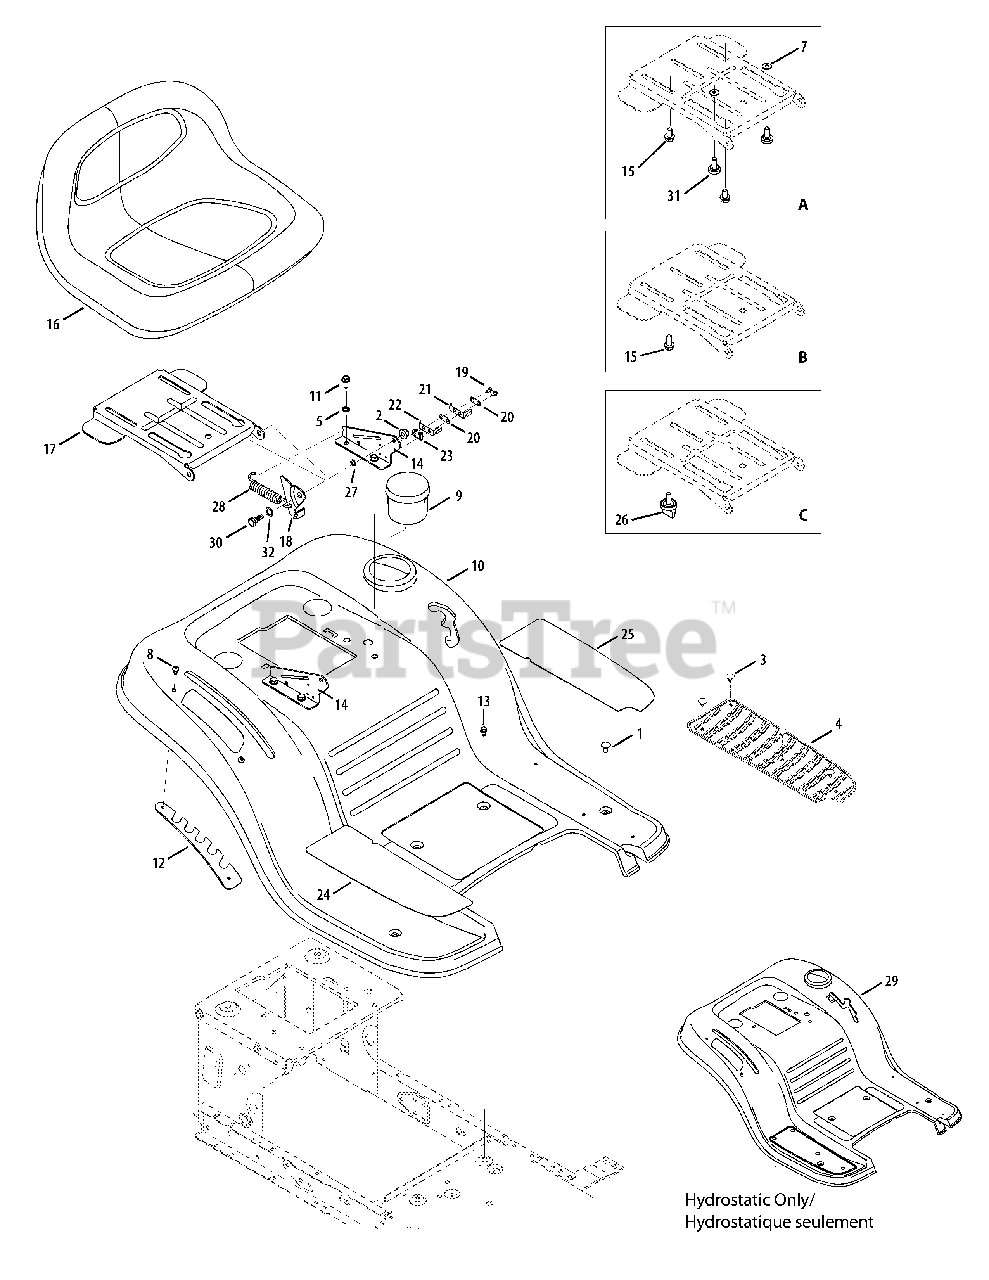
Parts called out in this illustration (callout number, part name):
1	Carriage Bolt 1/4-20 x .62
2	Flange Locknut 5/16-18 Gr. F, Nylon
5	Lockwasher 5/16 ID
6	Flat Washer .510 x .750 x .033
7	Flat Washer .405 x .875 x .059
7	Flat Washer .395 x .62 x .063
8	Tap Screw 1/4-20 x .50
11	S-Tapp Screw 5/16-18 x .75
13	Hex Wash S-Tapp Screw 1/4-20 x .50
15	Screw 3/8-16 x .875
16	Seat, Low Back
16	Seat, Medium Back
16	Seat, High Back
18	Seat Lift Bracket
19	Hex Wash HD AB S-Tapp Screw #8-.50
20	Insulator Plate
21	Spring Switch
22	Seat Spring Switch
23	Insulator Plate
24	Foot Pad, Abrasive, RH
25	Foot Pad, Abrasive, LH
27	Cupp. Washer .345 ID x .88 OD x .060
28	Extension Spring .84 Dia. x 4.6
30	Shoulder Screw
31	Shoulder Screw .625 x .175, 3/8-16
32	Flat Washer .510 x .75 x .033
